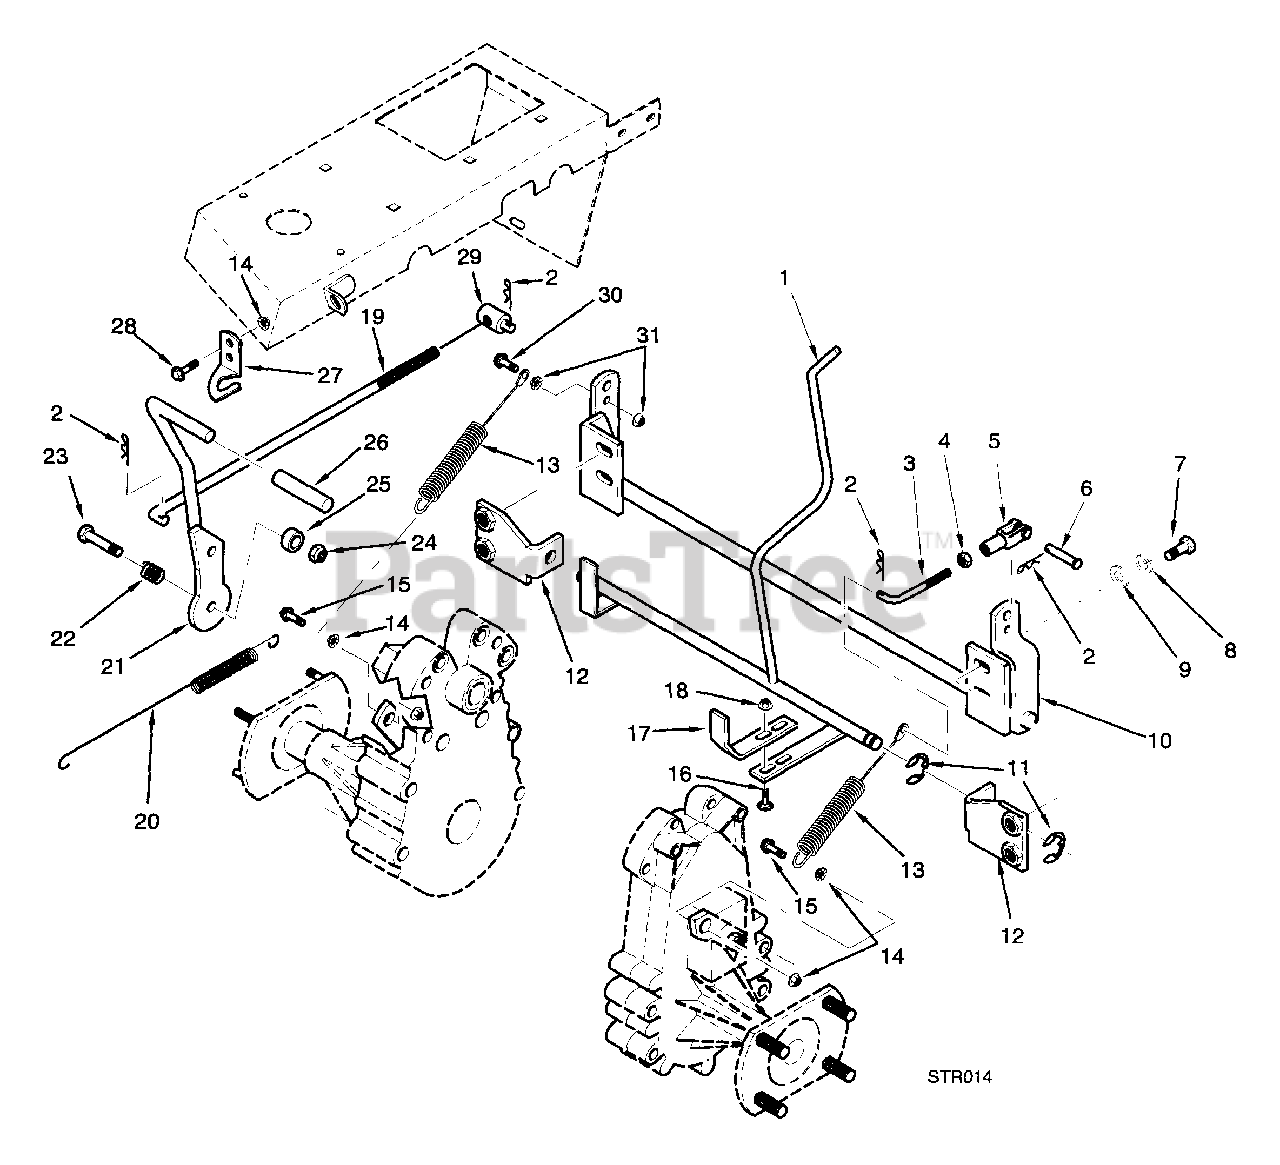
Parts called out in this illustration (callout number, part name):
1	Lever, Dump Valve
2	Hairpin
3	Rod, Brake - L.H.
4	Hex Nut, 1/4-28
5	Clevis
6	Pin, Clevis, 1/4 x 3/4"
7	Bolt, Hex Head, 3/8-16 x 1-1/2"
8	Lockwasher, 3/8"
9	Flatwasher, 3/8 (.391 x .938 x .105)
10	Actuator, Brake
11	Ring, Retainer
12	Mounting Bracket, Dump Valve
13	Cable Assembly, Parking Brake
14	Serr. Fl. Hex Nut, 5/16-18
15	Serr. Fl. Hex Head CPSCR, 5/16-18 x 1.00"
16	Carriage Bolt, 1/4-20 x 3/4"
17	Bracket, Dump Valve Lever
18	Serr. Fl. Hex Nut, 1/4-20
19	Rod, Brake - R.H.
20	Spring
21	Lever, Parking Brake
22	Spring, Control Detent
23	Bolt, Hex Head, 3/8-16 x 2-1/4"
24	Hex Locknut, Elastic Stop, 3/8-16
25	Spacer
26	Grip, Parking Brake Lever
27	Latch, Brake Lever
28	Serr. Fl. Hex Head CPSCRW, 5/16-18 x 3/4"
29	Swivel Joint
30	Bolt, Hex Head, 1/4-20 x 1-1/4"
31	Serr. Fl. Hex Nut, 1/4-20
